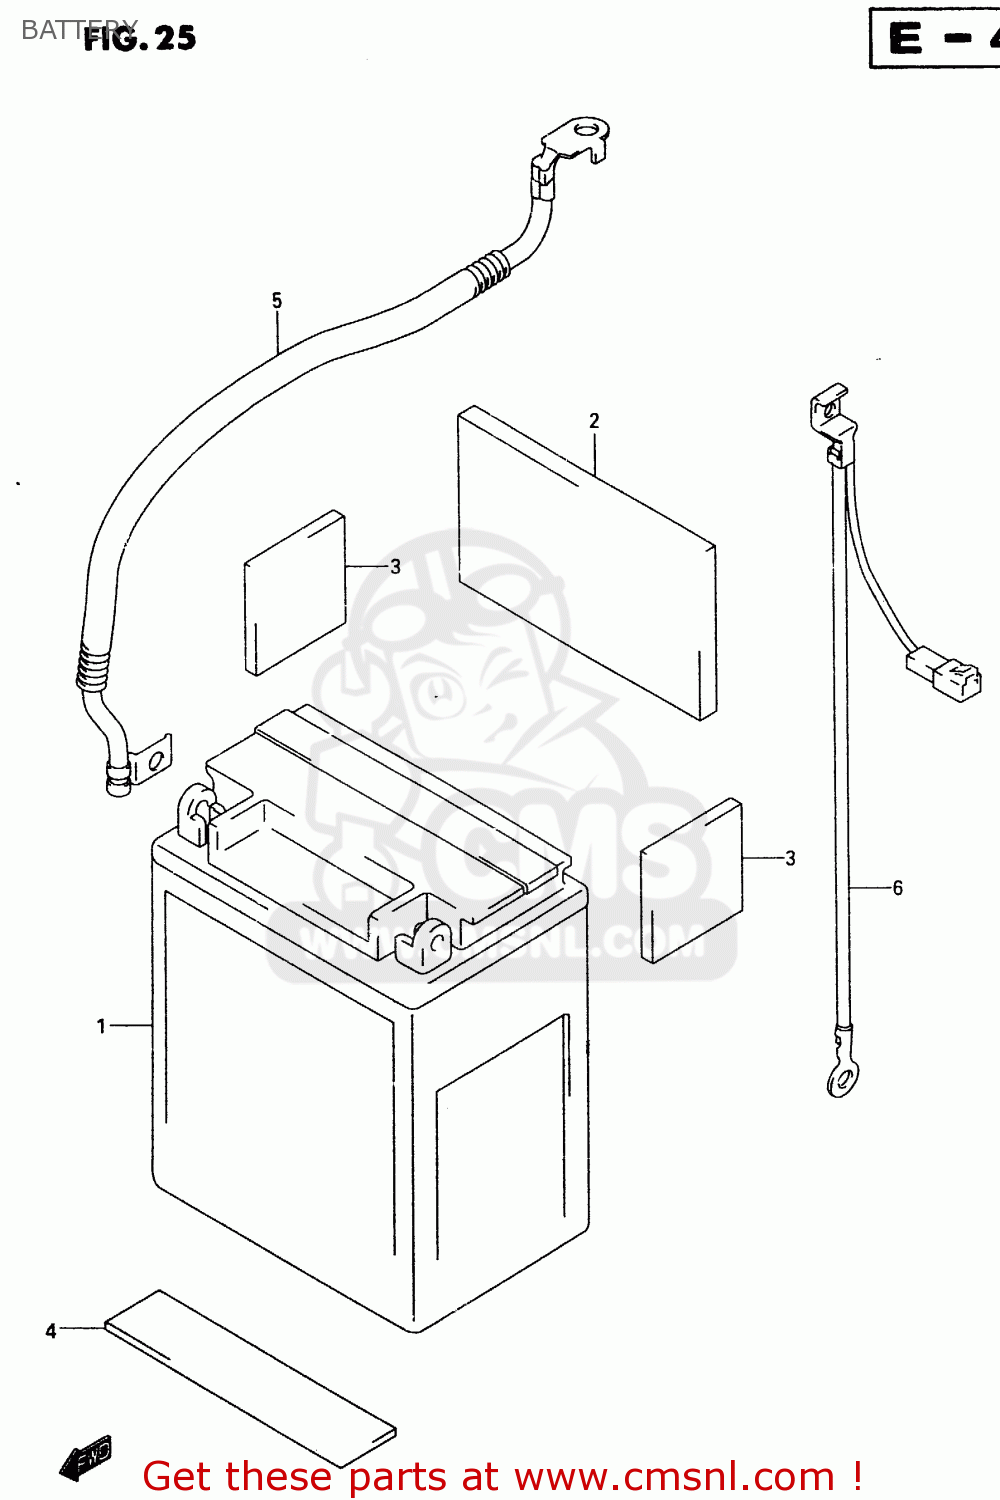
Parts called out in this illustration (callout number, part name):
1	BATTERY ASSEMBLY 12V14AH,F
2	PROTECTOR(50X50X5)
3	PROTECTOR(170X95X3.0)
4	CUSHION,BATTERY(80X27X3)
5	WIRE,BATTERY PLUS LEAD
6	WIRE,BATTERY MINUS LEAD
